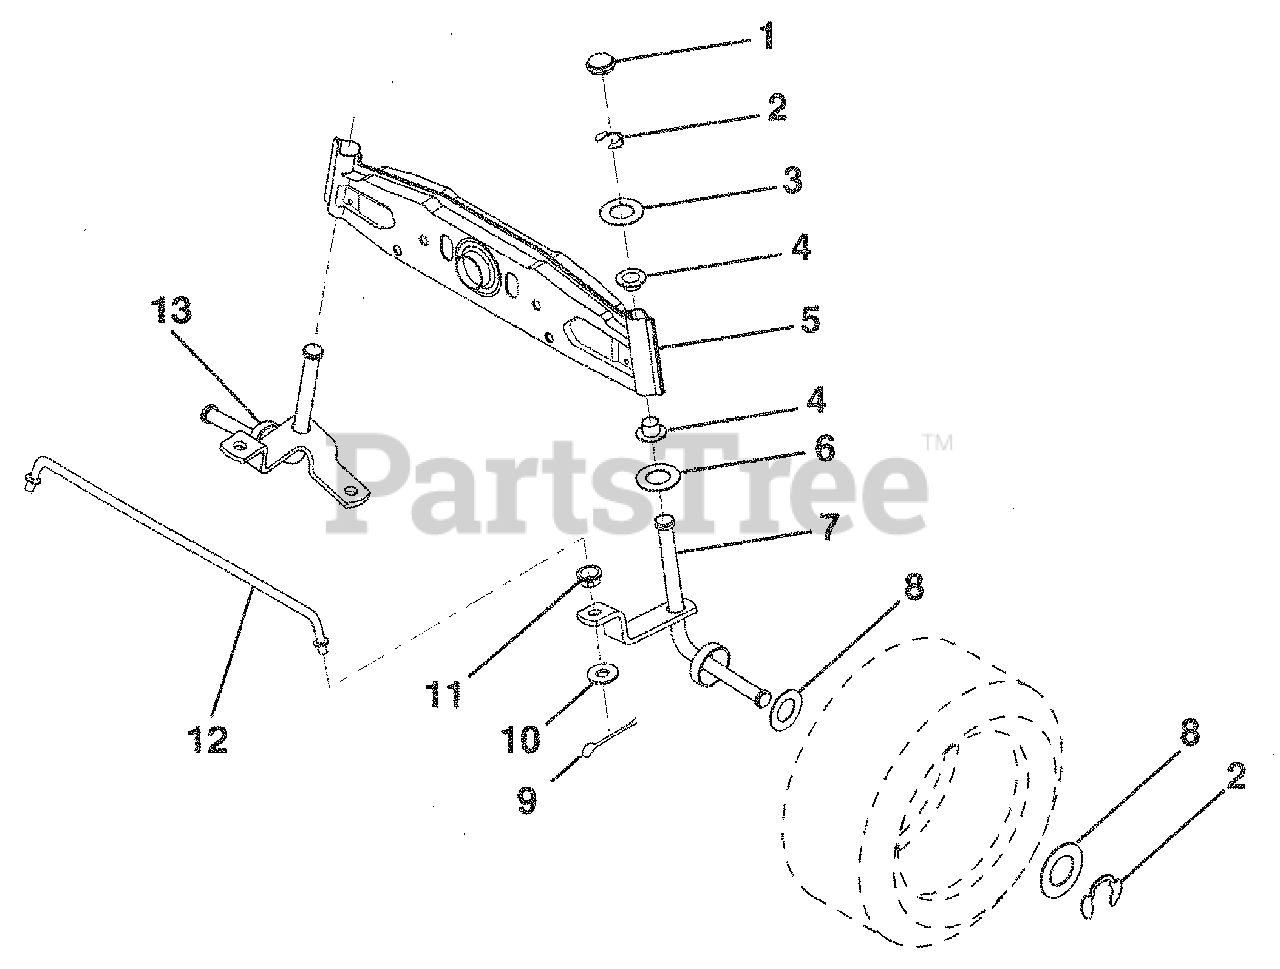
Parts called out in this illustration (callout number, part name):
1	Cap, Spindle
2	Ring, Clip
3	Washer 25/32 x 1 - 5/8 x 16 Ga.
5	Axle, Front
6	Bearing, Thrust
7	Spindle, R.H. Asm,
8	Washer 25/32 x 1-1/4 x 16 Ga.
9	Pin, Cotter 1/8 x 3/4
10	Washer 13/32 x 13/16 x 16 Ga.
13	Spindle, L.H, Asm.
